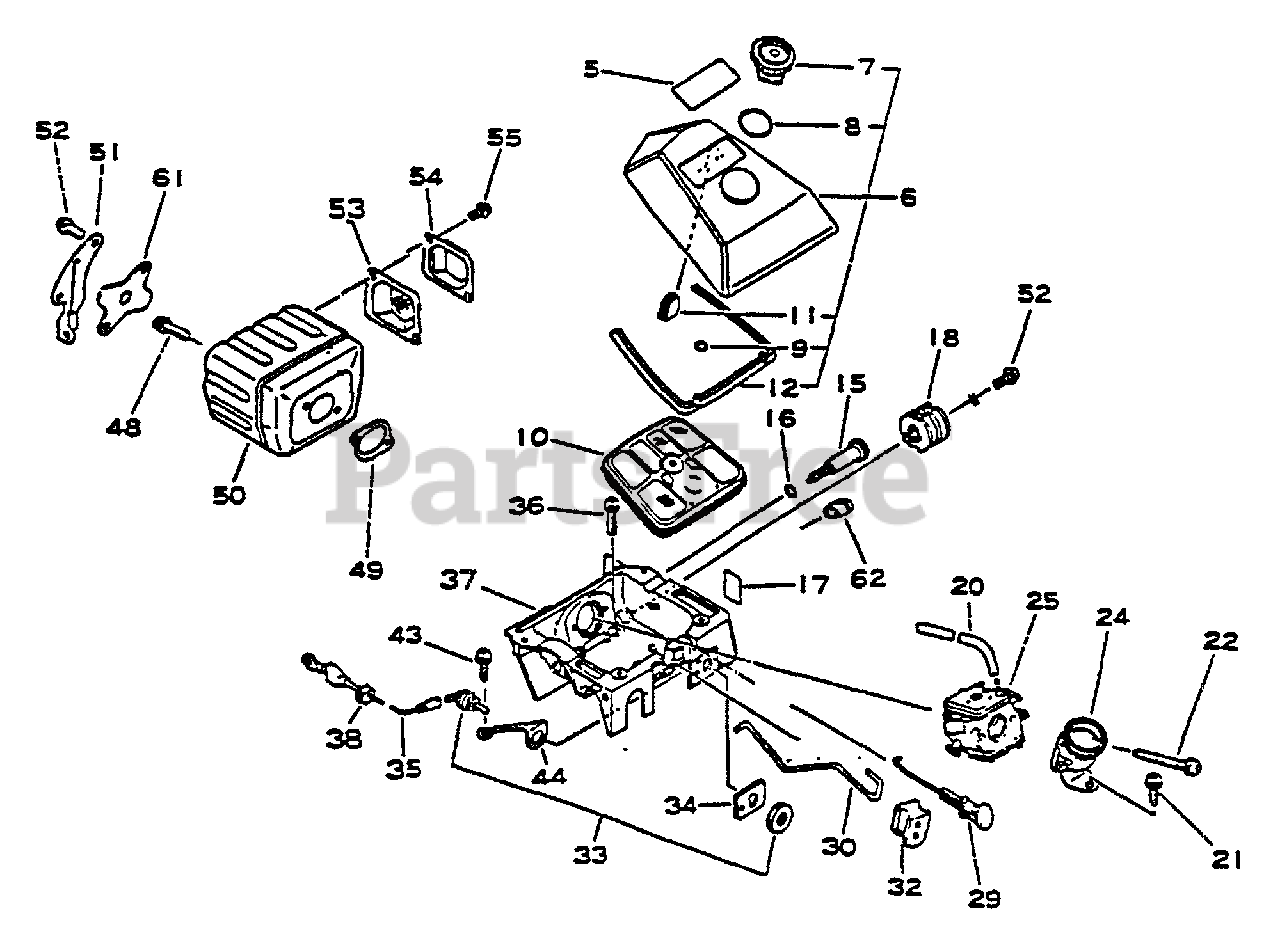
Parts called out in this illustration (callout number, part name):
5	LABEL
6	COVER ASSY, AIR FILTER
7	THUMBSCREW
8	O-RING 22
9	O-RING 10
10	FILTER ASSY, AIR
12	GASKET, AIR FILTER
15	SCREW, IDLE ADJUST - ORANGE
16	O-RING 7 MM
17	LABEL, CAUTION - IDLE
20	FUEL PIPE KIT
21	SCREW 5×14
22	SCREW 5×53
24	ADAPTOR, INTAKE
25	CARBURETOR
29	ROD, CHOKE
30	ROD, THROTTLE
32	ROD, THROTTLE
33	SWITCH, ON-OFF
34	LABEL, STOP
35	LEAD - GROUND
36	BOLT 5×20
37	CASE, CARBURETOR
43	BOLT 5×20
44	PLATE, GROUND
48	SCREW 5×20
49	GASKET, EXHAUST
50	MUFFLER
51	BRACKET, MUFFLER
52	SCREW 5×14
53	SCREEN, SPARK ARRESTER
54	OUTLET, EXHAUST
55	SCREW 4×10
61	COVER, MUFFLER
